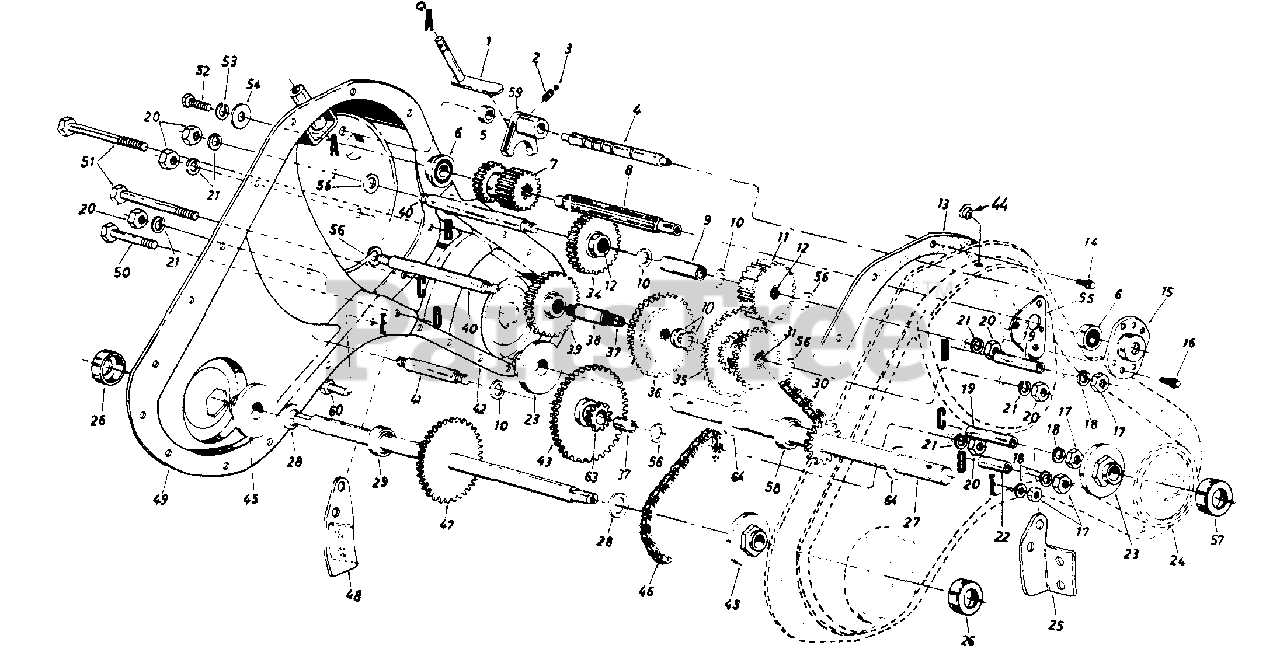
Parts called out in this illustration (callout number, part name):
1	Shifting Bracket Ass'y.
2	Compression Spring .50" Lg.
3	Ball Detent .250" Dia.
4	Detent Shaft 1/2" Dia.
5	Spacer .505" I.D. x .88" O.D.
6	Ball Brg. .62" I.D. x 1.38"
7	Spur Gear 16T (Input)
8	Input Spline Shaft 7/8"
9	Spacer .657" I.D. x 2.85" Lg.
10	Fl-Wash. .640" I.D. x 1.24"
11	Spur Gear 30T 7/8" I.D.
12	Needle Bearing 5/8" I.D.
13	Gasket - Trans. Hsg.
14	Hex S-Tap Scr. 1/4-20 x .5"
15	1-3/8" Dia. Bearing Housing
16	Hex TT-Tap Scr. 1/4-20 x .75"
17	Hex Nut 5/16-18 Thd.
18	L-Wash. 5/16" I.D.
19	Spacer 1.56" Lg.
20	Hex Nut 7/16-20 Thd.
21	Bell-Wash. .45" I.D. x 1.0"
22	Spacer 1.015" Lg.
23	Tine Shaft Brg. 1.002 x 2.50
24	Trans. Housing Ass'y. - L.H.
27	Tine Shaft Ass'y. 1" O.D.
28	Fl-Wash. .76" I.D. x 1.5" O.D.
29	Spacer .75" I.D. x .50" Lg.
30	Chain #50 5/8 Pitch x 52 Links - Endless
31	Needle Bearing 5/8" I.D.
34	Spur Gear 30T 12/16" I.D.
35	30/44T Gear Ass'y. Comp.
36	Spur Gear 44T
37	Sleeve Bearing
38	Gear Hub 3/4" I.D. x 3" Lg.
39	Spur Gear 30T 1.0" I.D. x 1/2" W
40	Jack Shaft 5/8" Dia. x 5"
41	Jack Shaft 5/8" Dia. x 2.38"
45	Wheel Brg. .752" x 2.5"
46	#420 Chain 1/2 Pitch x 50 Links - Endless
47	Wheel Shaft Ass'y. 15.6"
51	Hex Bolt 5/16-18 x 2.5"
52	Hex Bolt 1/4-20 x .62" Lg.
53	L-Wash. 3/8" I.D.
54	Fl-Wash. 1/4" I.D. x .93" O.D.
55	Gear Positioner Bracket
56	Fl-Wash. 7/16" I.D. x 1-3/8"
57	Dust Cover Ass'y. 1" Shaft
58	Spacer 1" I.D. x 2" O.D.
59	Shifting Fork
60	Hex Bolt 5/16-18 x .75" Lg.
63	10T Sprocket Ass'y.
64	Thrust Wash. 1.03" I.D. x 1.62" O.D.
